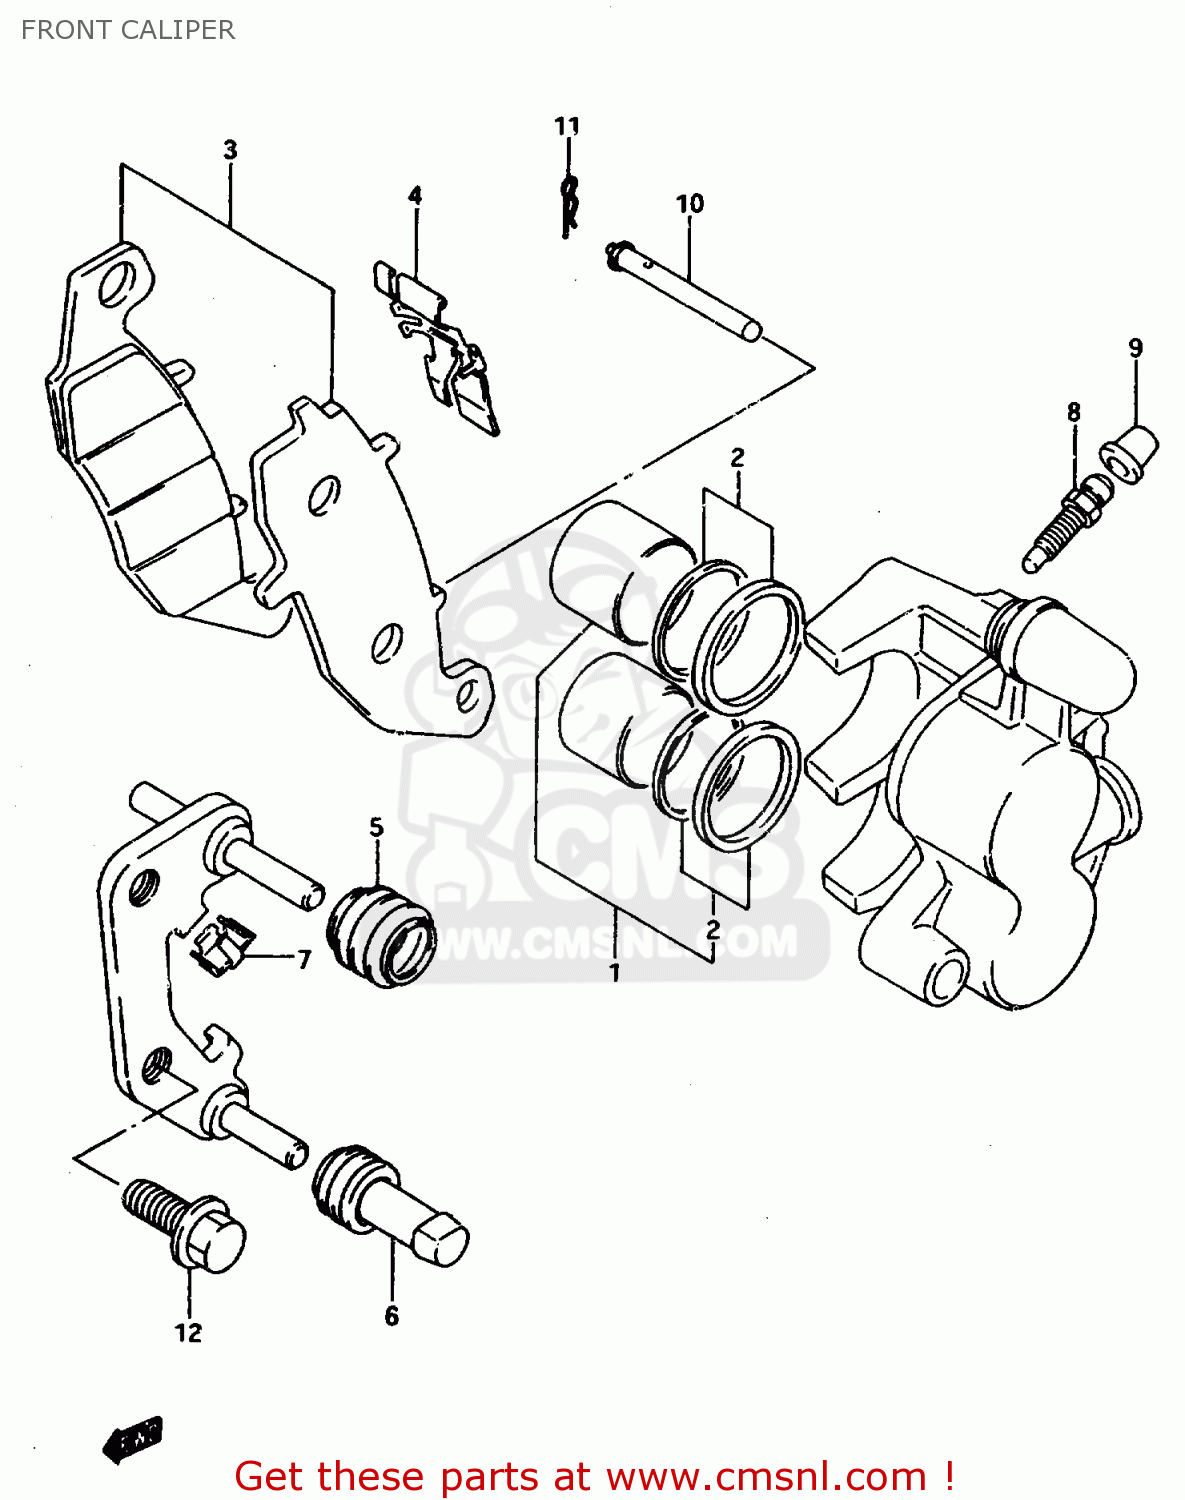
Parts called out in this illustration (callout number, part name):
1	PISTON SET
2	SEAL SET,PISTON
3	PAD SET (NAS)
4	SPRING,PAD,L
5	BOOT,AXLE
6	INSULATOR,AXLE
7	GUIDE,PAD
8	BLEEDER
9	CAP,BLEEDER PLUG
10	PIN,PAD
11	CLIP,PAD PIN
12	BOLT
